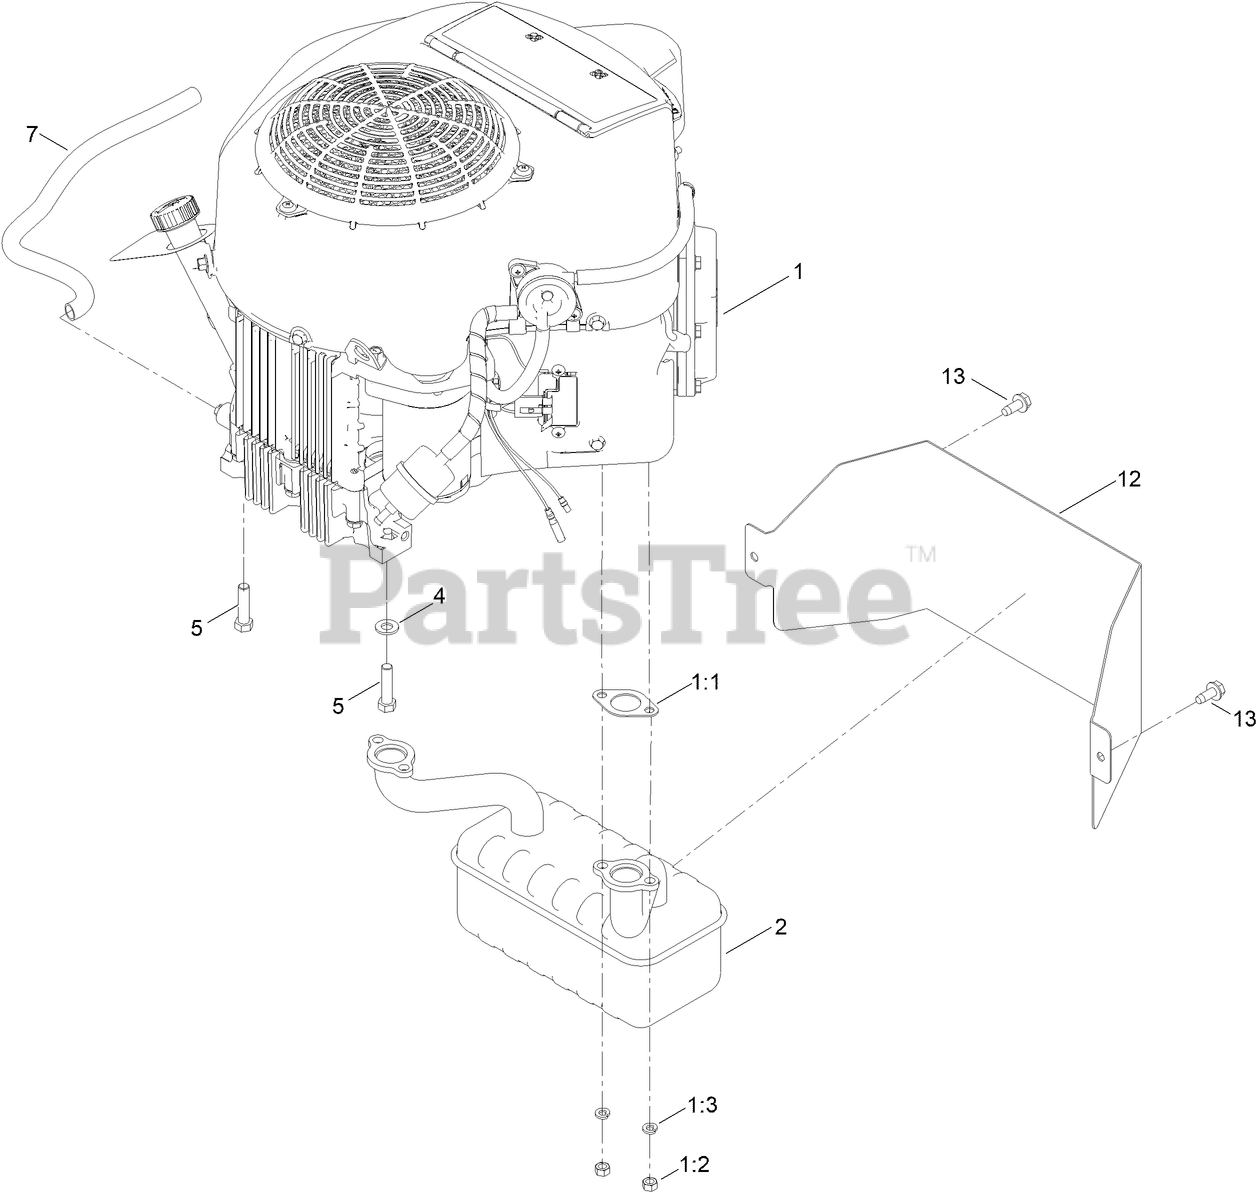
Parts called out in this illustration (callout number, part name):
1:1	GASKET-EXHAUST
1:3	WASHER-LOCK
2	MUFFLER
4	WASHER-FLAT
5	BOLT-HH
7	TUBE-DRAIN, OIL
12	HEAT SHIELD - MUFFLER
13	SCREW-HWHTF
